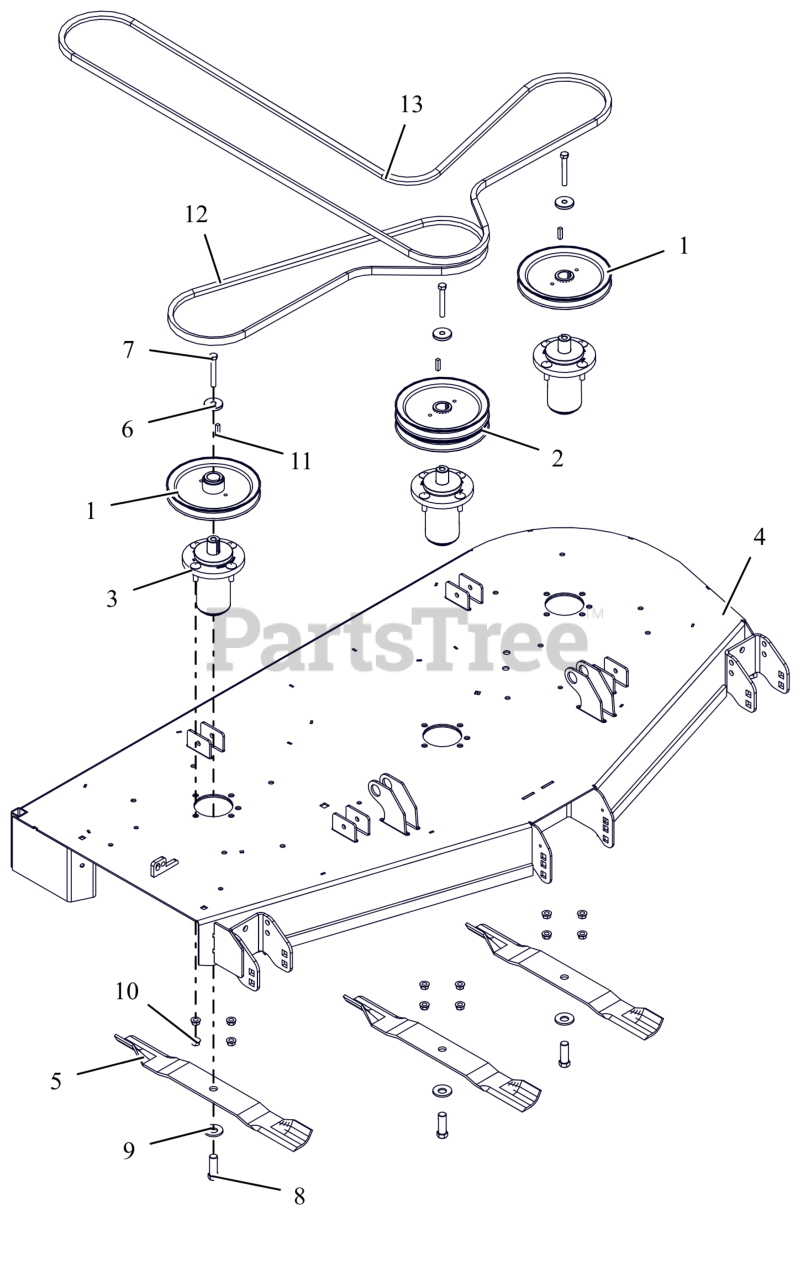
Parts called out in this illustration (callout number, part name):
1	PULLEY, V-7.50 OD X 1"ID
2	PULLEY, DOUBLE 1"X7.50"&7.50" (BLACK)
3	ASM, MAINT FREE ALUM SPINDLE
4	KIT,DECK-60" W/DECALS-GRAVELY
5	BLADE, 20.5"
6	RETAINER, SHEAVE
7	BLT, HEX .38-16X2.75 G8 ZCC
8	BLT, HEX .62-18X1.75 G8 ZCC
9	WSHR-BLVL .669X1.535X.138
10	NUT-LK-CTR-FLG .375-16 GF ZCC
11	KEY, SQ .25X.25X1.00 RC 40-50
12	V-BELT, B-COGGED
13	V-BELT, HB SECTION
